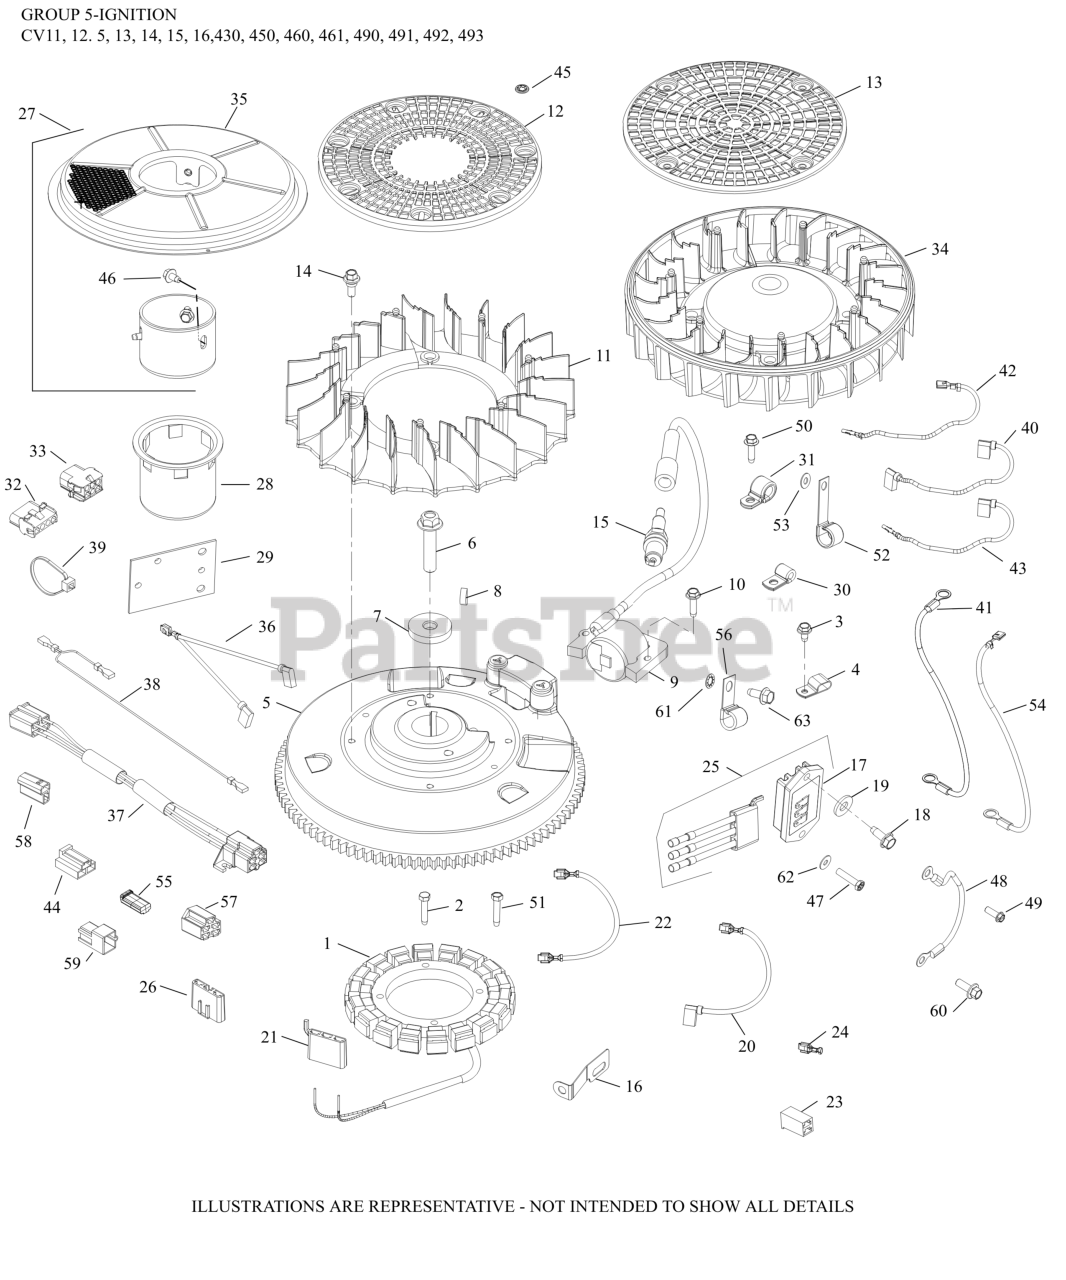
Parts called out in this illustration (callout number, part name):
1	KIT, 15 / 20 AMP STATOR
2	SCREW, M5X0.8X25 - (#25086402S)
3	SCREW, FLG THD FRM M5X.8X10
5	FLYWHEEL - USE 12 025 65-S
6	SCREW, FLG M10X1.5X45-USE 25 086 361-S
7	WASHER, FLAT 13/32"
8	KEY, 3/16" X 5/8"
9	MODULE, IGNITION
10	SCREW, FLG THD FRM M5X.8X20-(#25086399S)
11	FAN-(#DSC)
13	SCREEN,GRASS LOW PRFLE W/O HOLE
14	BOLT, SHOULDER
15	PLUG, SPARK (PRO SERIES)
16	BRACKET, GROUND STRAP
17	RECTIFIER-USE 12 755 111-S
18	SCREW,FLG THD FRM M6X1.0X16-(#25086397S)
21	CONNECTOR
23	CONNECTOR
